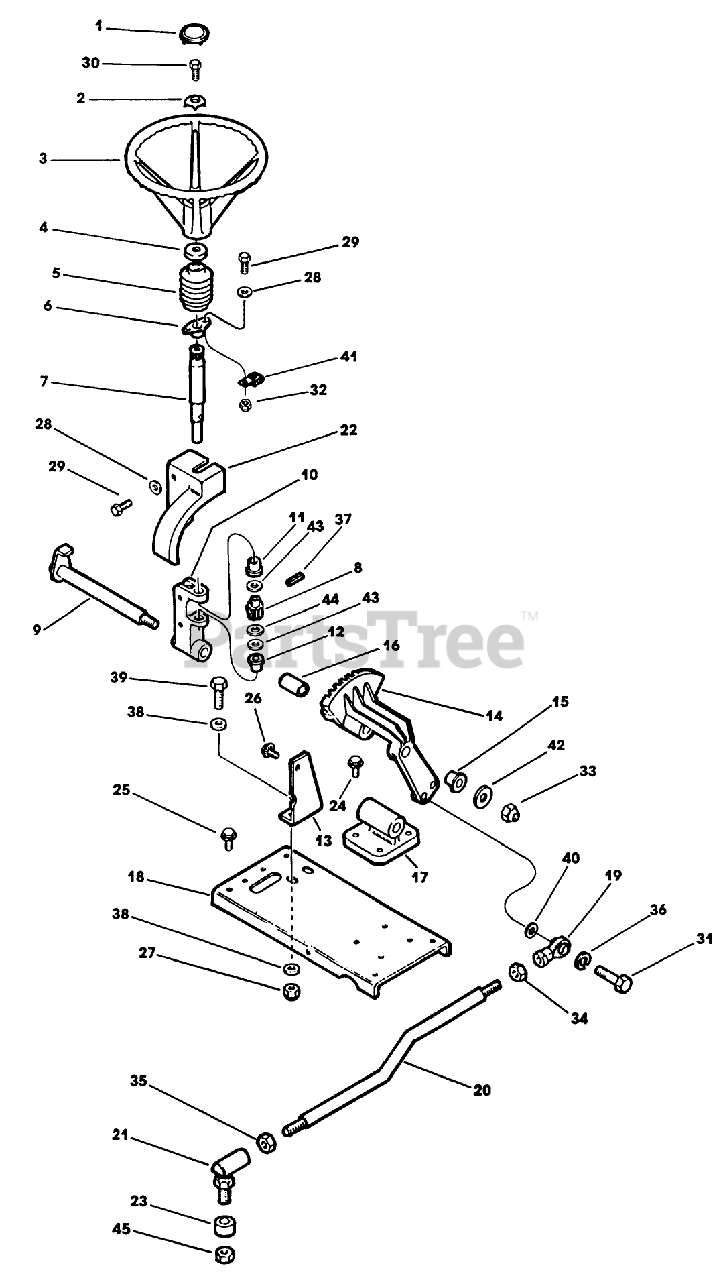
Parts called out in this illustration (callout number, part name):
1	CAP
6	BEARING AY.
8	GEAR - PINION
11	BUSHING
19	ROD END
21	BALL JOINT, RH
24	SCREW-THD ROLL, HWH
27	NUT-LOCKING
29	SCREW-HH
30	SCREW - HEX
32	NUT-LOCK, CONE
33	NUT-HEX
38	WASHER
41	CLAMP - J EX
43	WASHER
44	SPACER
